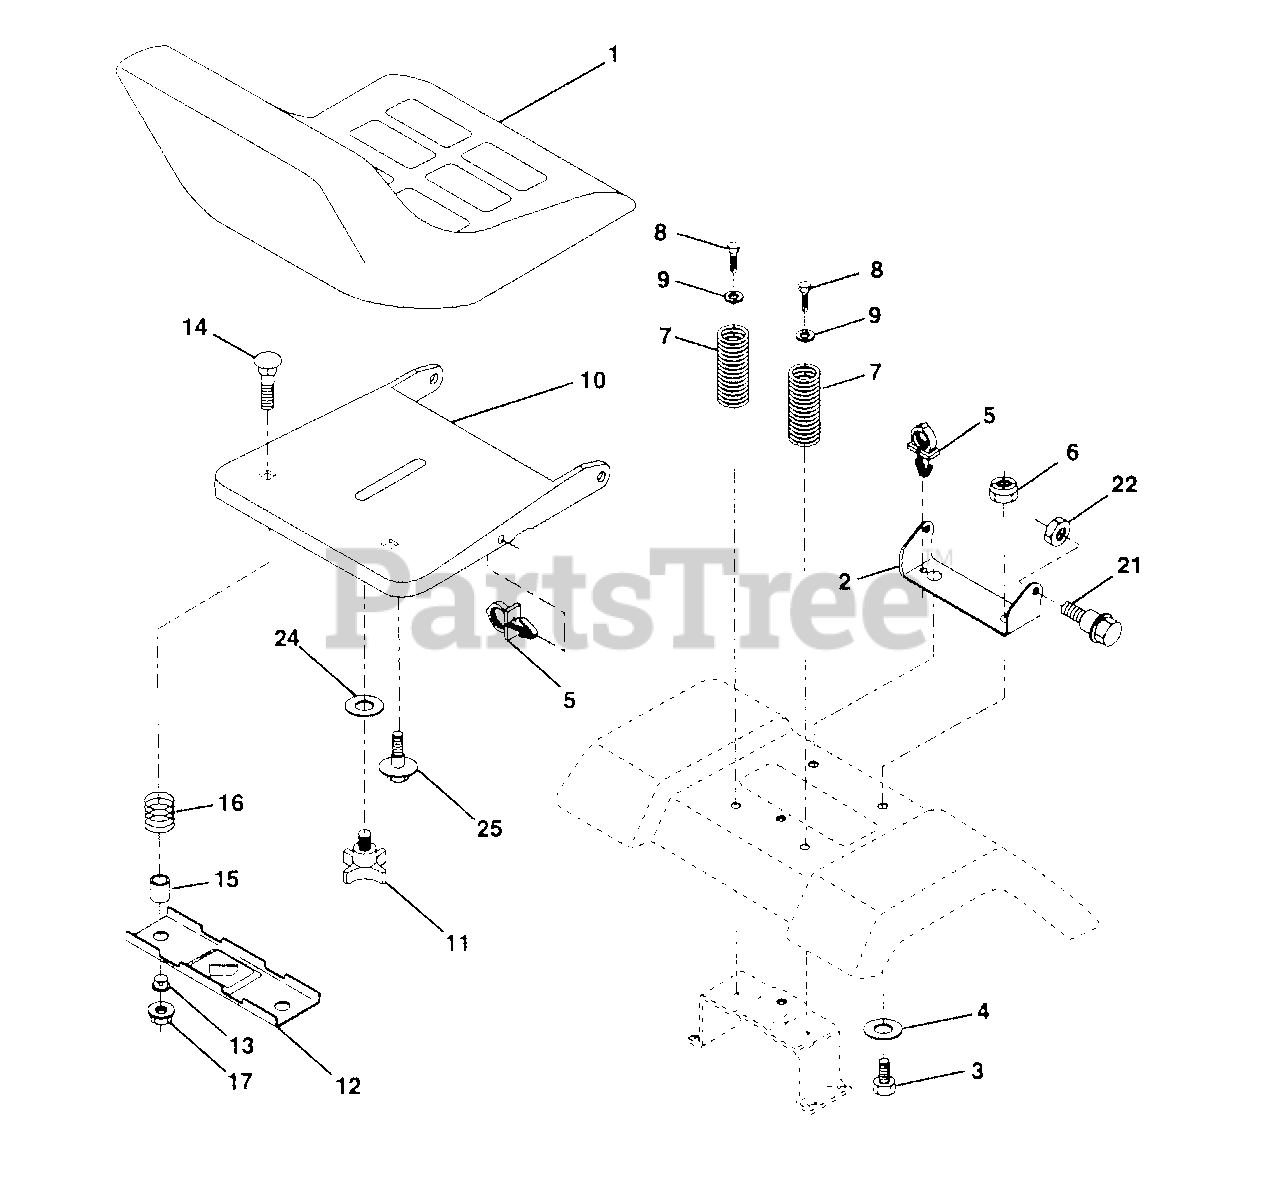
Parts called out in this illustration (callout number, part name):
1	Seat V450 Blk/blk Std
2	Bracket Pivot Seat 8 720
3	Bolt Fin Hex 3/8-16unc X 1
4	Washer 13/32 X 1 X 10 Ga
6	Nut Lock Hex w/Insert 3/8-16 Unc
7	Spring Seat Cprsn 2 250 Blk Zi
8	Screw Thdrol 3/8-16 X 1 Ty-tt
9	Washer 13/32 X 1 X 14 Ga.
10	Pan Seat
11	Knob Seat 1/2 - 13 Unc Blk
12	Bracket Mounting Switch
13	Bushing Snap Blk Nyl 50 Id
14	Bolt Rdhd Sht Nk 1/4-20x1-3/8
15	Spacer Split 28x 96 Yel Zinc
16	Spring Cprsn 1 27 Blk Pnt
17	Nut Lock 1/4 Lge Flg Gr 5 Zinc
21	Bolt Shoulder 5/16-18 Unc Blkz
22	Nut Hex Lock W/Ins 5/16-18
24	Washer 17/32 X 1-3/16 X 12 Ga.
25	Bolt Shoulder 5/16-18 X 62
